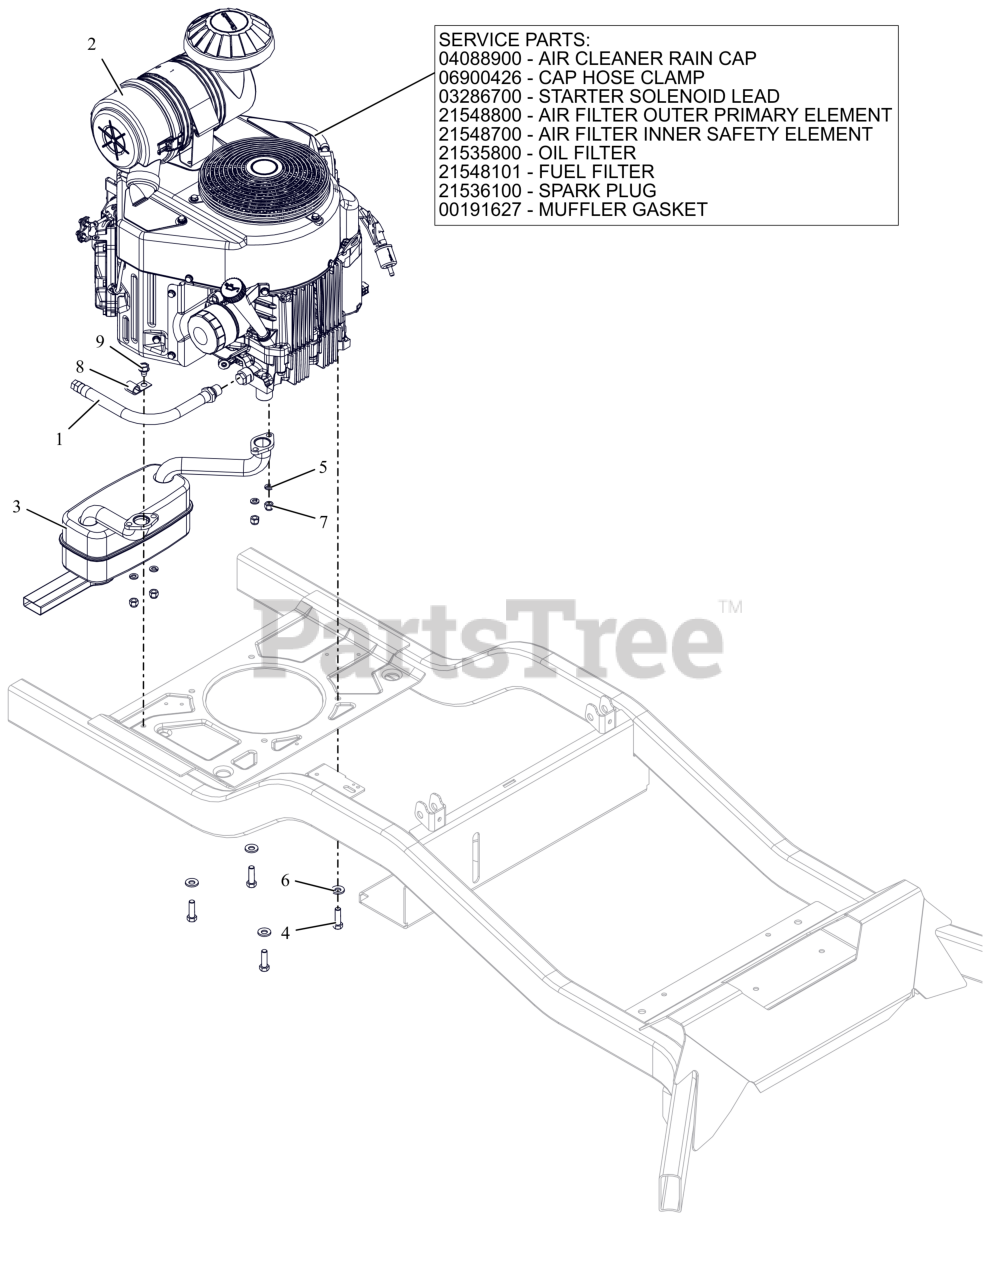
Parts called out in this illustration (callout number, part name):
1	HOSE, OIL DRAIN
2	ENGINE, KAWASAKI - FX730
2	CAP, KAW 11065-7025
2	CLAMP, HOSE #36 SS 1.813-2.75
2	LEAD - STARTER SOLENOID
2	FILTER, OUTER
2	FILTER, INNER - KAW
2	FILTER,OIL - KAW
2	FUEL FILTER-KAWASAKI FR
2	PLUG, SPARK
2	GASKET, MUFFLER S/O
3	MUFFLER, KAWASAKI
4	BLT, HEX .38-16X1.25 G5 ZCC NT
5	WSHR,LK-REG .312X.078 ZCC
6	WASHER, 3/8" SPRING DISC
7	NUT, LK-CTR-JAM M8-1.25 GR8.8 ZC120
8	J-CLAMP
9	SCR,TAP .375-16X.50 HWH TR ZCC
